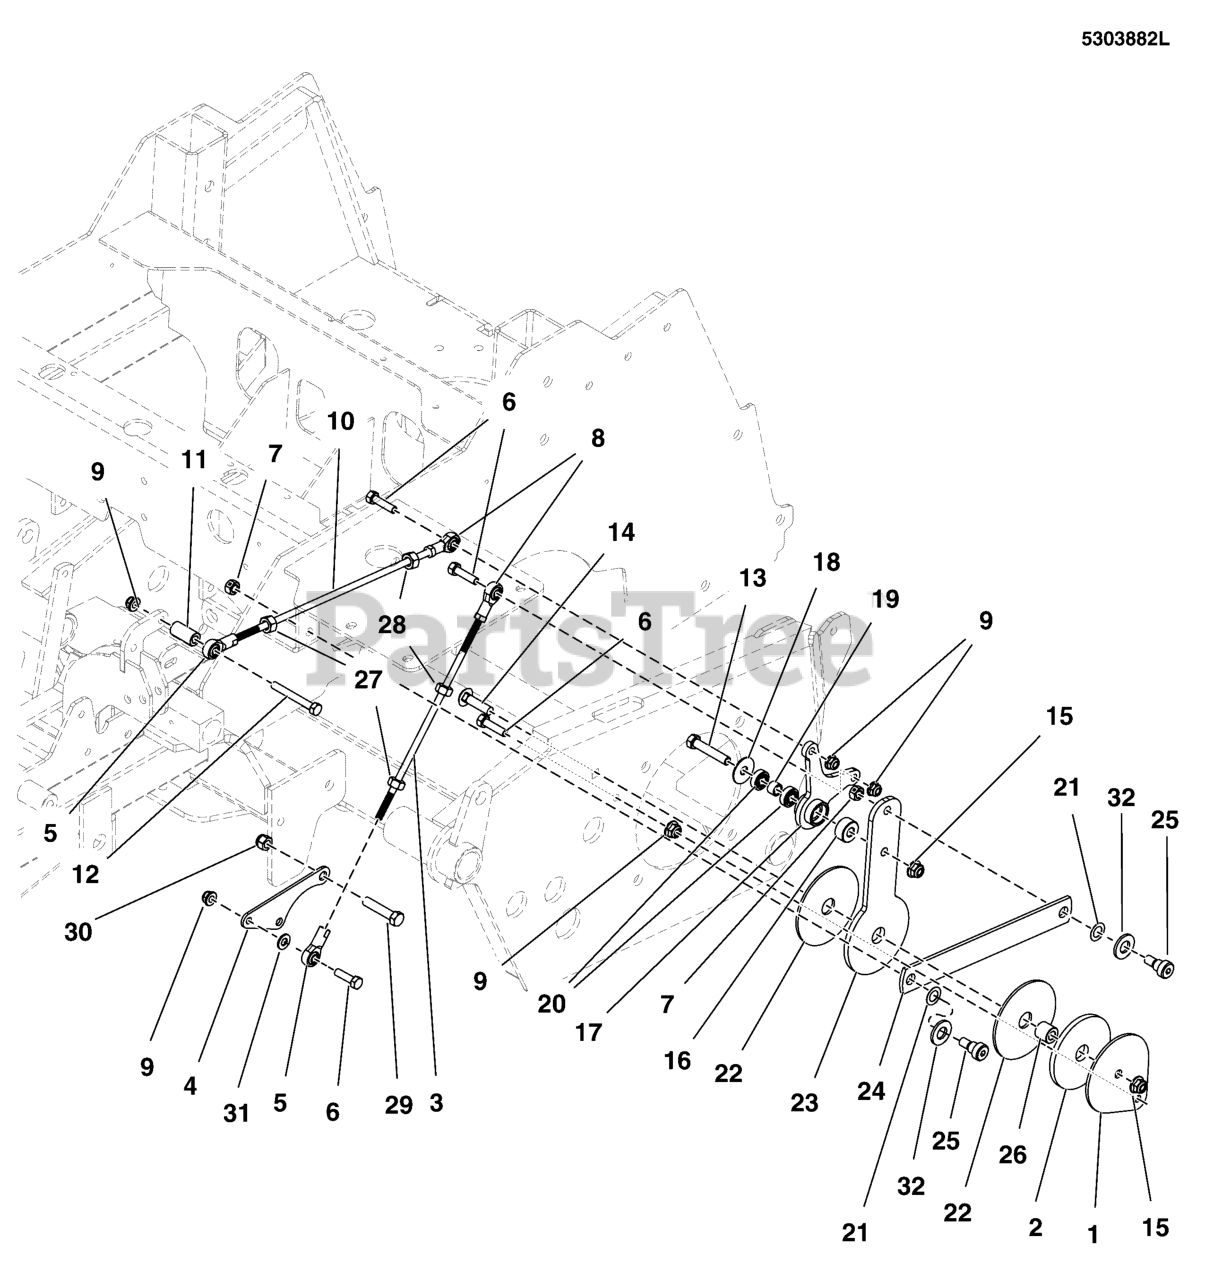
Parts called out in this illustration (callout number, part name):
1	PLATE, CONTROL SYSTEM LOCK - BLK
2	PAD, .77 X 3.50 X .25, POLYURETHANE
3	ROD, HYDRO LINKAGE
4	PLATE, CONTROL MOUNT - BLK
5	BALL JOINT 5/16-24 RH FEMALE BRONZE RACE
6	BOLT, 5/16-18 X 1-1/4 GD5 TFL, CZ
7	NUT, Hex, Side Lock, 3/8-16
8	BALL JOINT 5/16-24 LH FEMALE BRONZE RACE
9	NUT, 5/16-18 HEX NYLOCK FLANGE NUT
10	ROD, HYDRO LINKAGE, 14.63
11	SPACER, .38 X .75 X 1.25, PM, CZ
12	BOLT, 5/16-18 X 2-1/2" GD5 YZ
13	BOLT, 3/8-16 X 2-1/2" GD5 CZ
14	BOLT, 3/8-16 X 1-1/2, CARRIAGE, GD5, CZ
15	NUT, 3/8 - 16 HEX NYLOCK FLANGE
16	SPACER, .39 X 1.00 X .50, PM, CZ
17	PIVOT, CONTROL SYSTEM, S125XT
18	WASHER, 3/8" Fender
19	SPACER, .39 X .55 X .38, PM, CZ
20	BEARING, .375" ID X .875" OD X .341" THK
21	WAVE WASHER, 1/2"ID X 087"OD X .01 THK.
22	PAD, CONTROL SYSTEM
23	PLATE, CONTROL SYSTEM ARM - HT
24	LINK, CONTROL SYSTEM ARM, IS2100 - BLK
25	BOLT, 3/8-16 X 3/8", 1/2" SHOULDER
26	SPACER, .39 X .75 X .69, PM, CZ
27	NUT, Hex, 5/16-24
28	NUT, 5/16-24 HEX, LH
29	BOLT, 7/16-14 X 3/4, GD 5 YZ
30	NUT, 7/16-14 HEX TOP LOCK
31	WASHER, 5/16" SAE
32	WASHER, 1/2" GD9 YZ
